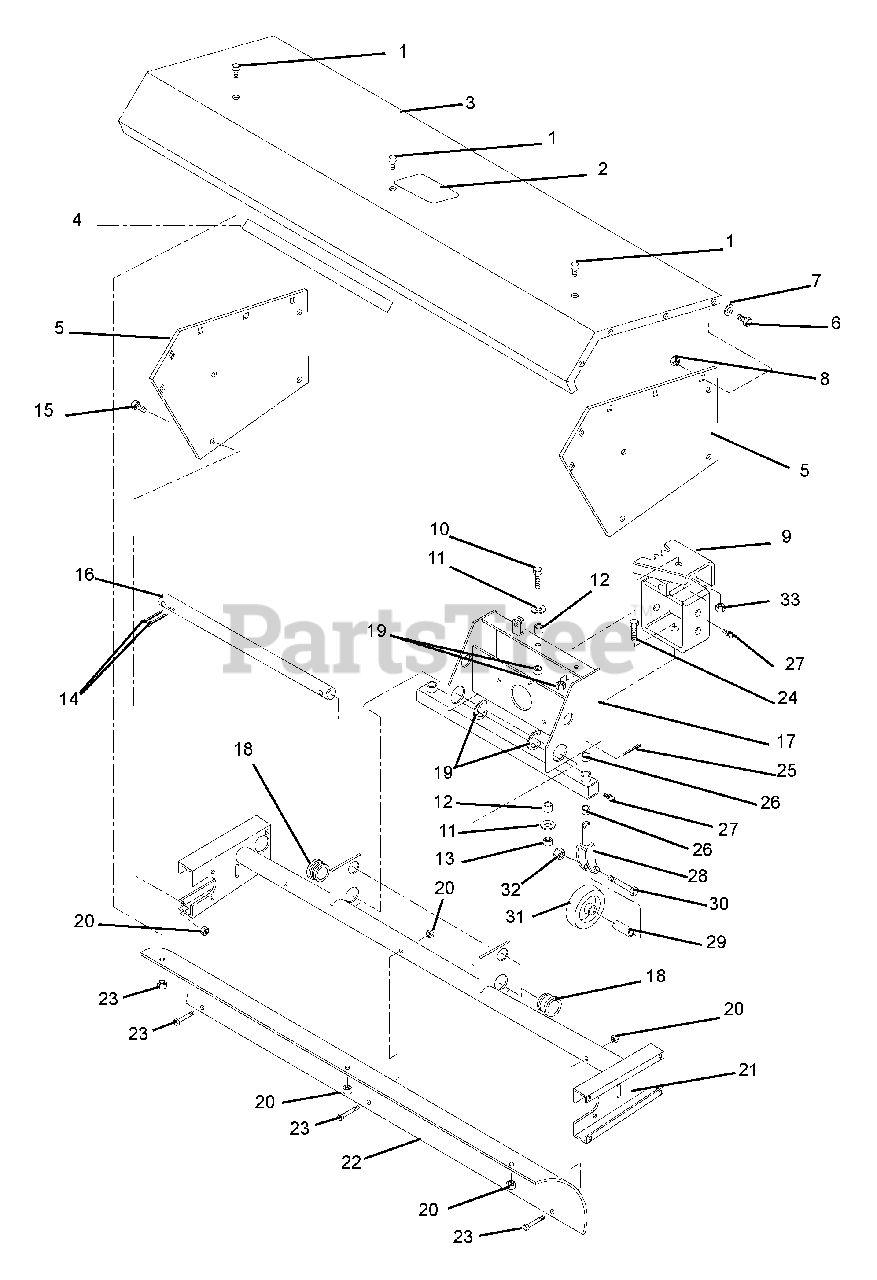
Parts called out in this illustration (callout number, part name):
1	Bolt-Hex .25-20 x .50 Grade 5
2	Decal-Caution
3	Hood
4	Decal-Gravely Logo
5	Plate-Side
6	Bolt-Hex .31-18 x .75 Grade 5
7	Washer-Flat-Steel .344 x .688 x .065
8	Nut-Locking-Center .31-18
9	Weldment, Power Brush Pivot
10	Bolt-Hex .50-13 x 1.50 Grade 5
11	Washer, Flat-Steel .531 x 1.06 x .095
12	Bushing, Sleeve .532 x .750 x .550
13	Nut-Locking-Center .50-13
14	Pin, Cotter .12 x 1.50
15	Bolt, Hex .31-18 x .75 Grade 5
16	Anchor-Threaded Adjustment
17	Weldment, Pivot Frame
18	Bushing, Flange 1.38 x 1.62 x 1.25
19	Ring-Retaining-External 1.880 x .062
20	Nut-Locking-Center .25-20
21	Frame-Brush Support
22	Shield
23	Bolt-Hex .25-20 x 2.25 Grade 5
24	Bolt-Hex .50-13 x 1.75 Grade 5
25	Pin-Cotter .12 x 1.25
26	Bushing-Sleeve, .752 x .877 x .75 Bronze
27	Fitting-Lube .25-28 x .256
28	Weldment, Caster Fork
29	Bushing, Sleeve .515 x .745. x 2.59
30	Bolt, Hex .50-13 x 3.75 Grade 5
31	Wheel-Caster
32	Nut-Locking-Center .50-13
33	Nut-Locking-Cone .50-13
